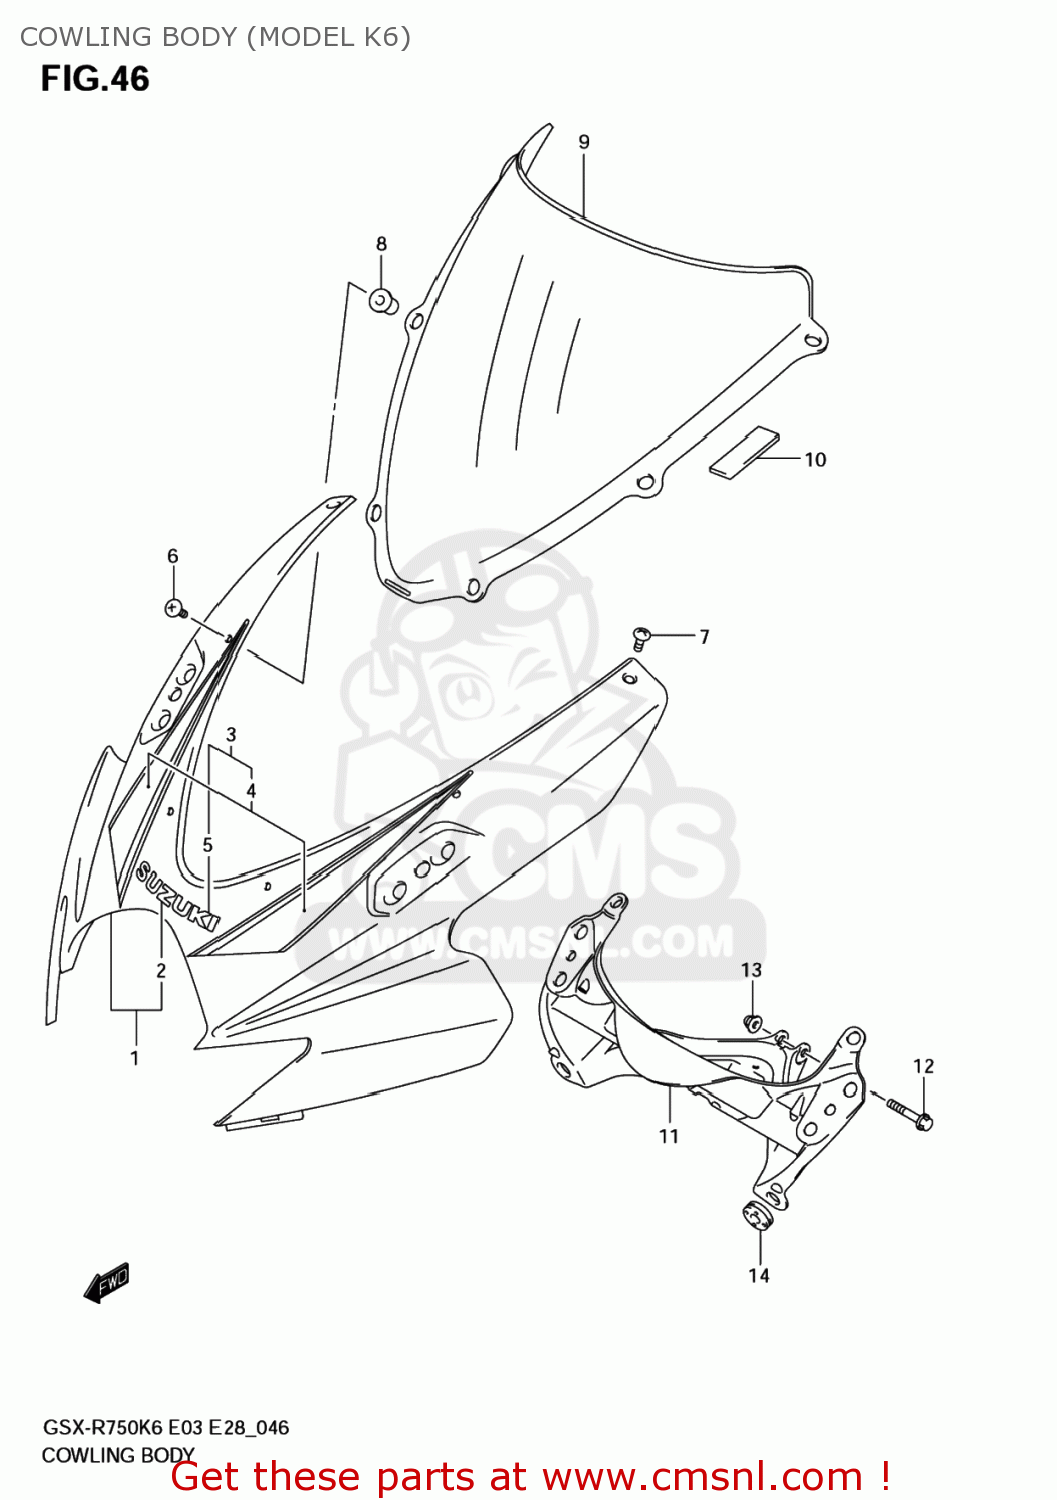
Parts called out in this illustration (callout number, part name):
1	BODY ASSY,COWLING
2	EMBLEM,SUZUKI
3	BODY ASSY,COWLING
4	TAPE SET,BODY COWL
5	EMBLEM,SUZUKI
6	SCREW(5X18)
7	SCREW(5X15)
8	NUT
9	WINDSCREEN COM
10	TAPE(6X25X0.13)
11	BRACE,COWLING
12	BOLT
13	NUT
14	CUSHION
